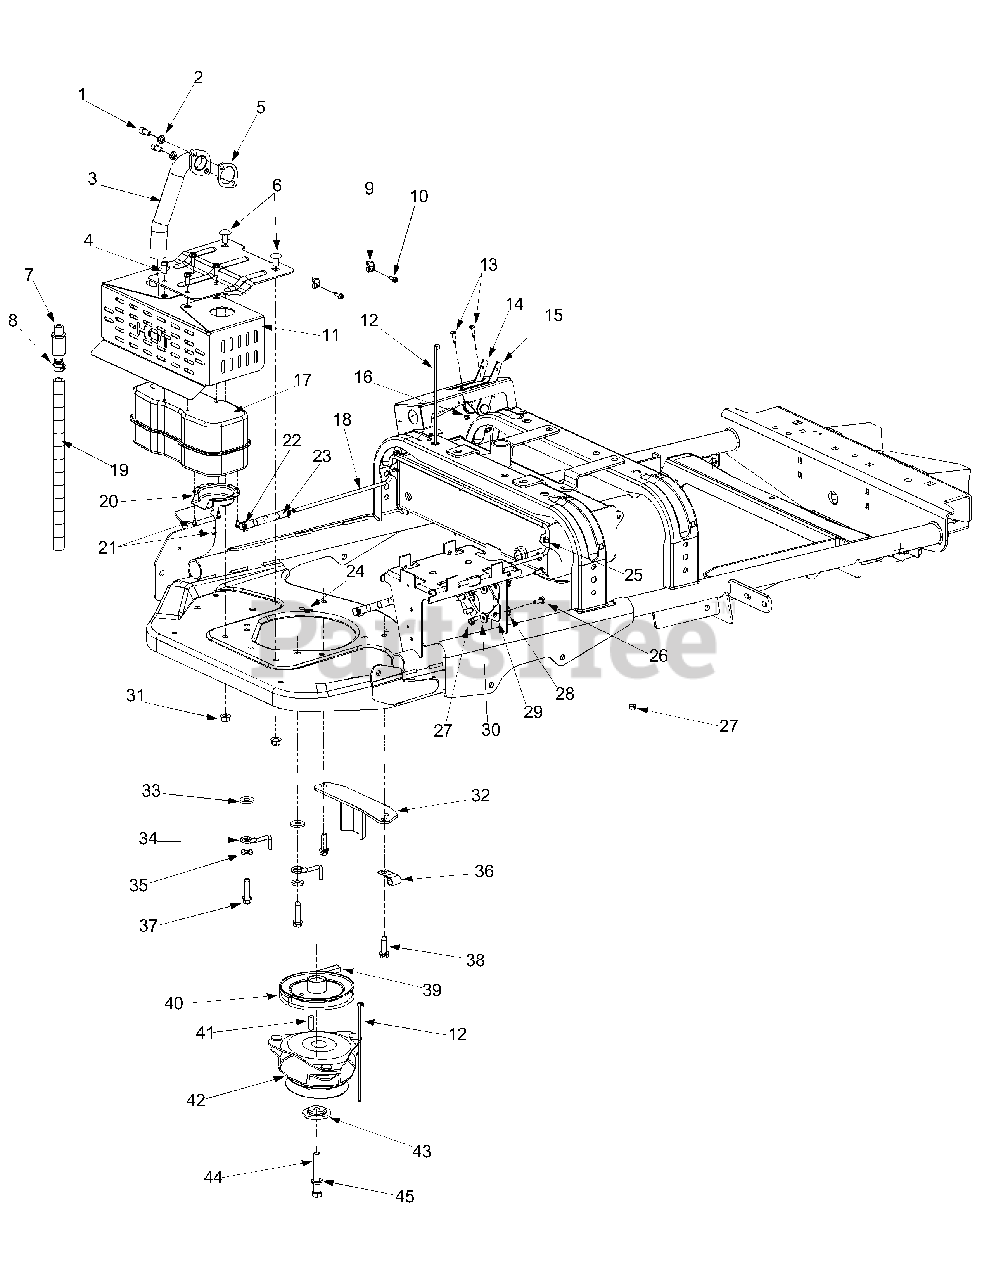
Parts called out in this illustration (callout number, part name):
1	Cap Screw 5/16-18
2	Lock Washer 5/16
3	Exhaust Pipe
4	Hex Washer Screw 1/4-20 x .75
5	Exhaust Gasket
6	Carriage Bolt 3/8-16 x .75
7	Oil Drain
8	Oil Drain Cap
9	Throttle Clamp
10	Hex Washer Screw #10-32 x .625
13	Screw #10-24 x .75
14	Throttle Cable Control 32"
15	Choke Cable Control 32.25"
16	Hex Lock Nut #10 - 24
17	Muffler
19	Oil Drain Hose
20	Muffler Deflector
21	Hex Washer Screw #8-32 x .375
23	Fuel Line Hose
24	Lock Washer 5/16
25	Retainer Clip
26	Hex Cap Screw 1/4-20 x .620
27	Hex Lock Nut 1/4-20
28	Lock Washer 1/4 ID x 3/4 OD
29	Solenoid
30	Bell Washer .265 ID x .75 OD
31	Flange Lock Nut 3/8-16
34	Rear Belt Retainer Rod
35	Flat Washer .407 ID x .812 OD
36	Heat Shield Cable Clip
37	Hex Washer Screw 3/8-16 x 1.5
38	Hex Washer Screw 3/8-16 x 1.25
39	V-Belt
40	Pulley
42	Electric Clutch
43	Spacer Clutch
44	Hex Cap Screw 7/16-20 x 3.0
45	Lock Washer 7/16
